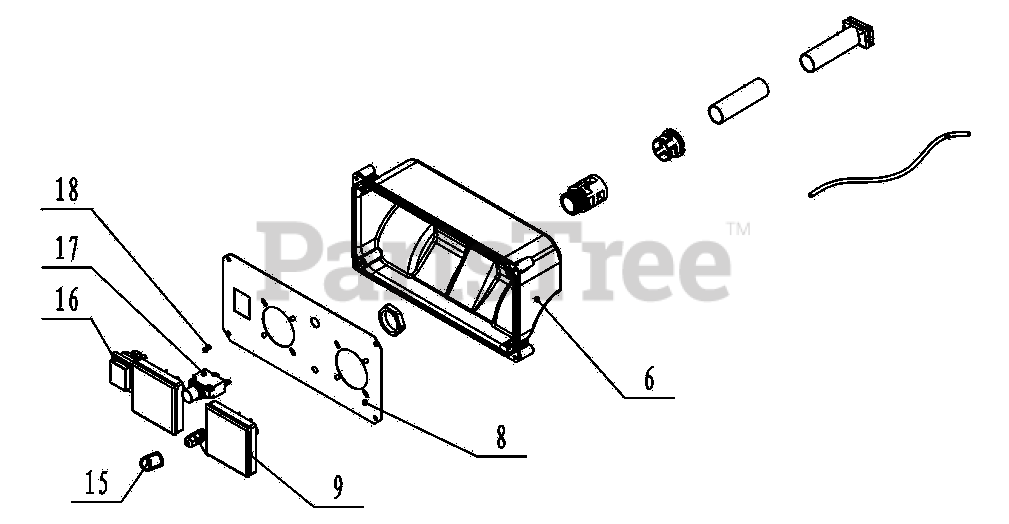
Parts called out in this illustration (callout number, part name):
6	BACK BOX C-PNL 1.8/3.25KW
8	FACEPLATE CONTRL PANEL GP2600
9	RECEPTACLES 250V 15A
15	COVER, WATERPROOF
16	SWITCH, ON/OFF ROCKER
17	BREAKER, CIRCUIT, 12A
18	SCREW PPPH #8-16 X .66" BZC
